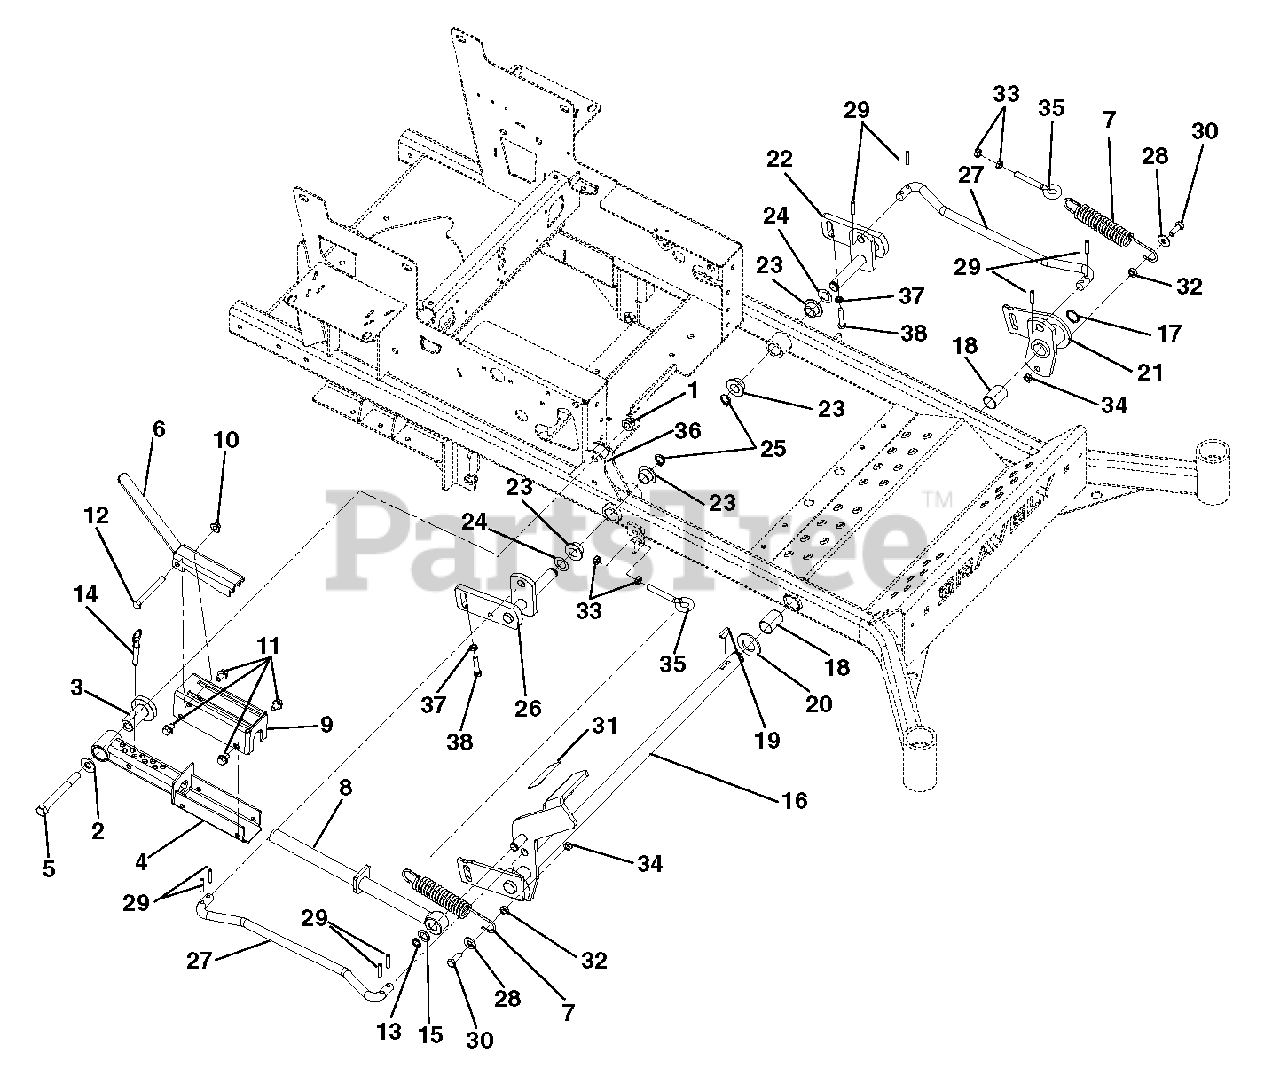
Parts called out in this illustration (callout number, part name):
1	@NUT-LK-NYL-FLG .50-13 YWZC
2	WSHR-FL-STL .531X1.250X.10 YWZ
3	BEARING, PEDESTAL
4	WMT, MECHANICAL LIFT
5	@BLT-HEX .50-13X4.50 GR5 YWZC
6	MECH DECK LIFT LOCK LEVER- BLK
7	SG-TENS .162X1.25X8.25 WLD 25
8	WMT, MECH. LIFT SHAFT (.62)
9	WMT, MECH LIFT COVER
10	@NUT-LK-NYL-FLG .38-16 YWZC
11	@SCR-TAP .38-16X.50 HWH TR YWZ
12	@BLT-HEX .38-16X3.25 GR5 YWZC
13	RG-RTNG-EXT .625X.050
14	PIN, SPRING BALL .375OD X 1.50
15	WSHR-FL-STL .630X1.005X.062 YZ
16	WMT, 100I FOOT OPER DECK LIFT
17	RG-RTNG-EXT 1.00X.078
18	BSHG,1.00ID X 1.125OD X 1.50LG
19	KEY-WDRF .25X1.00 HRD #15
20	WSHR-FL-STL- 1.062X2.0X.134 YZ
21	WMT, LH FRONT MOWER LIFT
22	WMT, LH REAR DECK LIFT ARM
23	BSHG-FLG .762X1.0X.580X1.48 NY
24	WSHR-HDND-THRST .758X1.23X.031
25	RG-RTNG-EXT .689X.078
26	WMT, RH REAR DECK LIFT ARM
27	ROD-LIFT ASSIST 16.35"
28	@WSHR-FL-STL.438X1.00X.083 YWZ
29	PIN-ROLL .250X1.25 STNLESS STL
30	@BLT-HEX .38-16X1.00 GR5 YWZC
31	GRIP, PEDAL 1.50 X 3.00
32	BSHG-SLV .377X.624X.235
33	NUT-HEX-JAM .375-16 YWZC
34	@NUT-LK-CTR-JAM .375-16 YWZC
35	BLT-EYE .375-16X2.50 YWZC
36	SPACER .516X1.000X.875
37	NUT- JAM .312-18 YWZC
38	BLT-HEX .312-18X1.50 FTH GR5YZ
